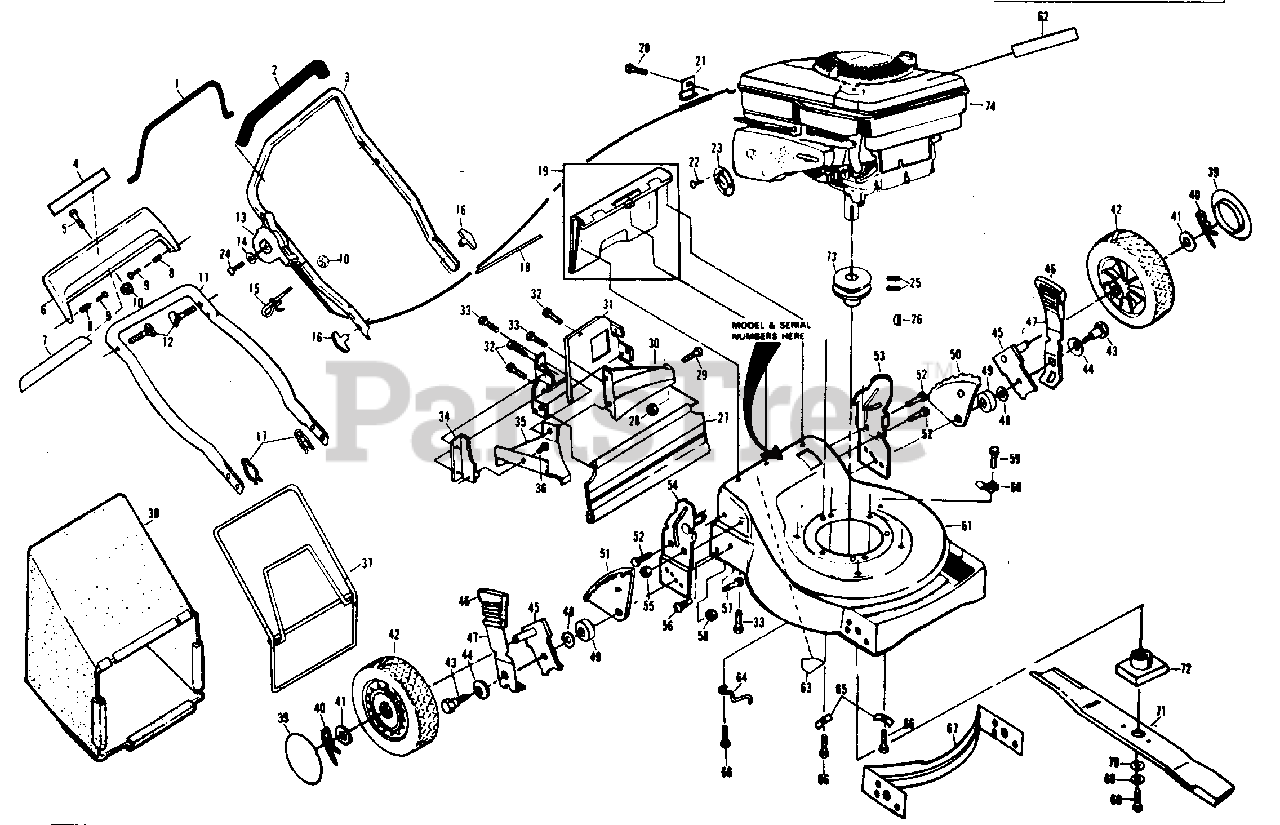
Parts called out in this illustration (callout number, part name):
1	Control Bar (AYP part number)
2	Handle Grip (AYP part number)
3	Upper Handle
4	Trim Plate Decal 5.0 HP
5	Hex Washer Head Screw (AYP part number)
6	Trim Plate
7	Trim Plate Decal (AYP part number)
8	Nylon Bushing (AYP part number)
9	Tapping Screw (AYP part number)
10	Locknut (AYP part number)
11	Lower Handle (AYP part number)
12	Handle Bolt
13	Throttle Control
14	Flat Washer (AYP part number)
15	Rope Guide (AYP part number)
16	Handle Knob (AYP part number)
17	Hairpin Cotter (AYP part number)
18	Hinge Rod (AYP part number)
19	Rear Door Kit (AYP part number)
20	Thread Rolling Screw (AYP part number)
21	Cable Clamp (AYP part number)
22	Screw (AYP part number)
23	Muffler Deflector
24	Round Head Screw
25	Set Screw (AYP part number)
26	Hi-Pro Key #HP 505 (AYP part number)
27	Rear Skirt (AYP part number)
28	Locknut (AYP part number)
29	Truss Head Screw (AYP part number)
30	Rear Baffle (AYP part number)
31	Back Plate
32	Self Tapping Screw (AYP part number)
33	Hex Tapping Screw (AYP part number)
34	Side Baffle (AYP part number)
35	Discharge Baffle
36	Hex Head Screw (AYP part number)
37	Catcher Frame
38	Grass Bag Assembly
39	Hubcap (AYP part number)
40	Retainer Clip (AYP part number)
41	Flat Washer (AYP part number)
42	Wheel & Tire Assembly (AYP part number)
43	Shoulder Bolt (AYP part number)
44	Belleville Washer (AYP part number)
45	Axle Arm Assembly (AYP part number)
46	Selector Knob (AYP part number)
47	Selector Spring (AYP part number)
48	Flat Washer (AYP part number)
49	Spacer (AYP part number)
50	Wheel Adjusting Bracket (Left)
51	Wheel Adjusting Bracket (Right)
52	Thread Cutting Screw (AYP part number)
53	Handle Bracket Assembly (Left) (AYP part number)
54	Handle Bracket Assembly (Right)
55	Locknut (AYP part number)
56	Hinge Screw (AYP part number)
57	Carriage Bolt (AYP part number)
58	Locknut (AYP part number)
59	Hex Washer Head Screw (AYP part number)
60	Housing Cable Guide (AYP part number)
61	Lawn Mower Housing
62	"Poulan" Decal (AYP part number)
63	Danger Decal (AYP part number)
64	Belt Snubber (AYP part number)
65	Engine Washer (AYP part number)
66	Hex Head Thread Rolling Screw (AYP part number)
67	Front Baffle (AYP part number)
68	Hex Head Screw Grd. 8
69	Helical Lockwasher (AYP part number)
70	Hardened Washer (AYP part number)
71	Blade 22"
72	Blade Adapter (AYP part number)
73	Engine Pulley (AYP part number)
